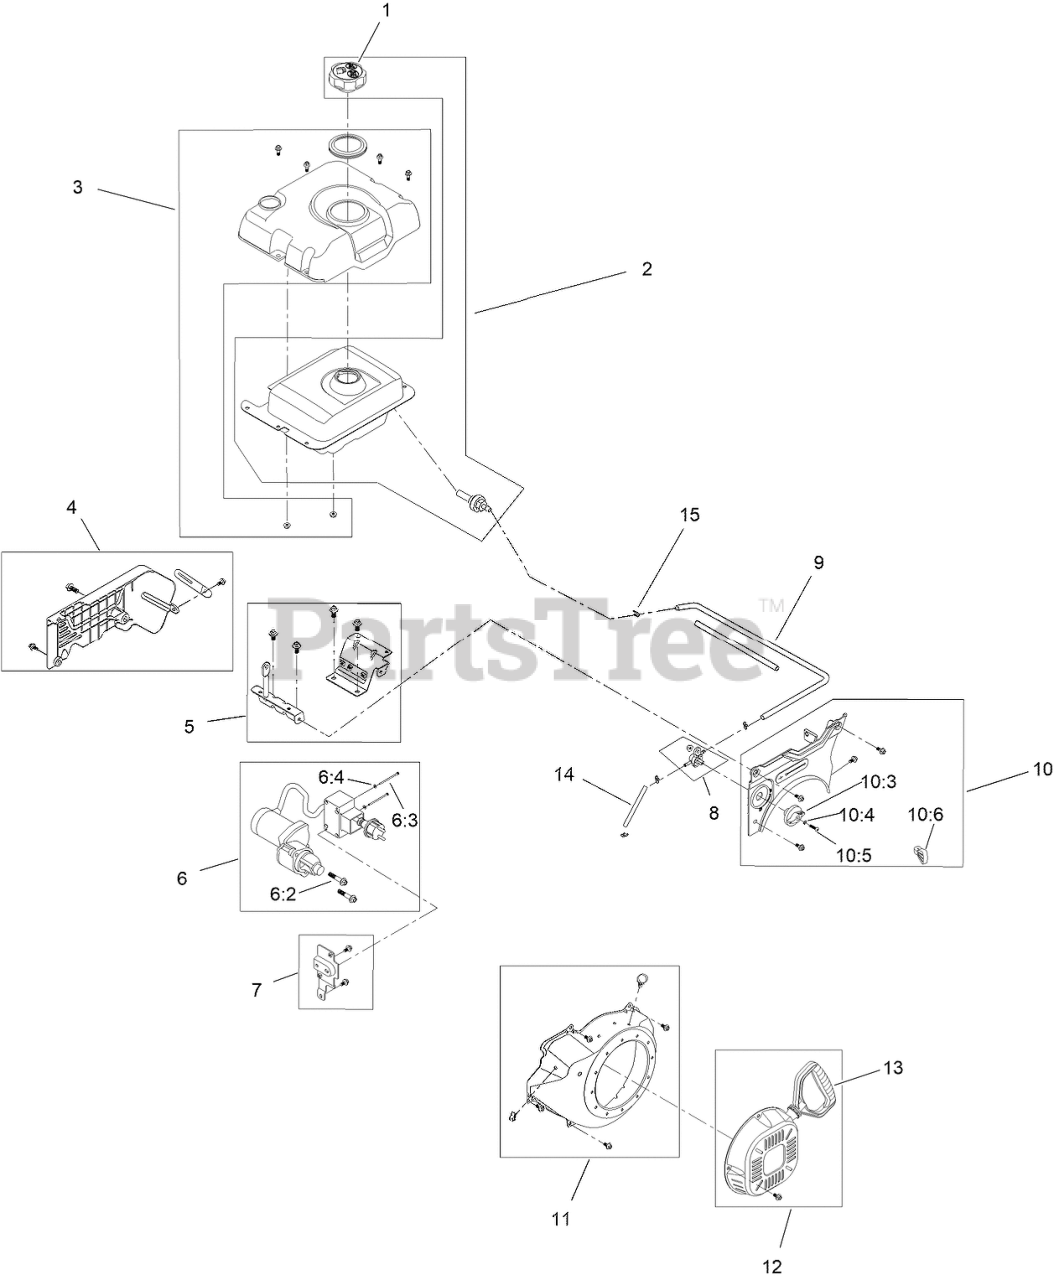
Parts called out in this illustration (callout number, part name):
1	CAP-FUEL
2	FUEL TANK AND CAP KIT
3	FUEL TANK COVER KIT
4	REAR PANEL AND HARDWARE KIT
5	TANK MOUNT BRACKET KIT
6	ELECTRIC STARTER KIT
6:2	SCREW-HHF
6:3	SCREW-BHP
6:4	WASHER-PLAIN
7	SWITCH BOX BRACKET KIT
8	FUEL SHUT-OFF VALVE KIT
9	HOSE-FUEL
10	FRONT PANEL KIT
10:3	KNOB-VALVE, FUEL
10:4	WASHER-PLAIN
10:5	SCREW-BHP
10:6	KNOB-CONTROL, THROTTLE
11	RECOIL SHROUD KIT
12	RECOIL KIT
13	HANDLE-RECOIL
14	HOSE-FUEL
15	CLIP-HOSE
